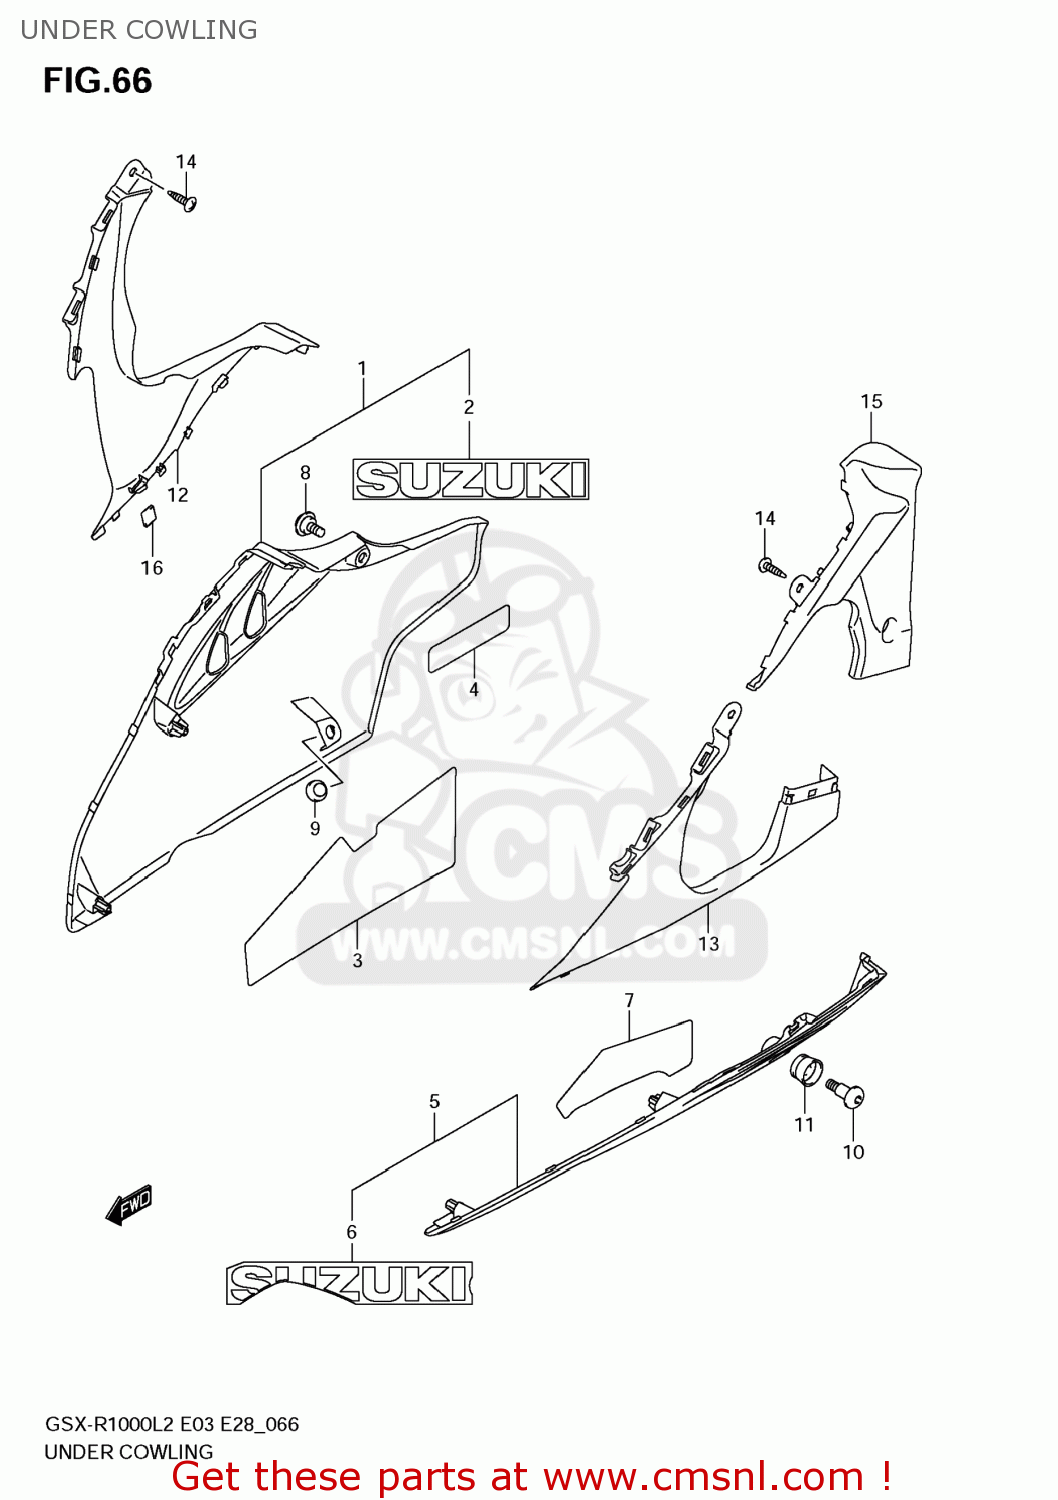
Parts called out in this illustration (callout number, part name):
1	COWLING,UNDER,R(WHITE)
2	EMBLEM,SUZUKI
3	SHIELD,UNDER COWL HEAT,R
4	SHIELD,HEAT
5	COWLING,UNDER,L(WHITE)
6	EMBLEM,SUZUKI,L
7	SHIELD,UNDER COWL HEAT,L
8	SCREW(5X13)
9	CUSHION
10	SCREW(6X20)
11	CUSHION,UNDER COWLING,L
12	COWLING,SIDE LWR,R
13	COWLING,SIDE LWR,L
14	SCREW
15	COVER,SIDE COWL,L
16	CUSHION,RR COVER NO.2
